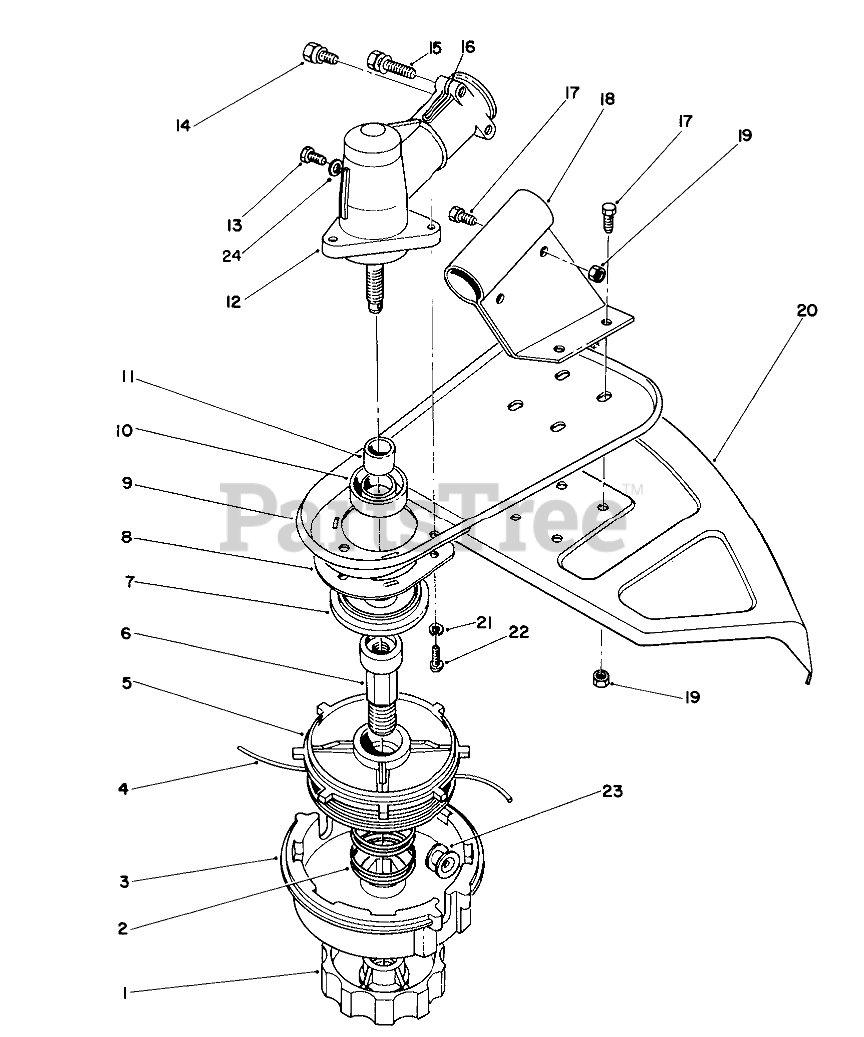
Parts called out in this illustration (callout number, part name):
1	LH KNOB(SERVICE ONLY)
2	SPRING (SERVICE)
3	SPOOL HSG (SERVICE ONLY
5	INNER SPOOL(SERV ONLY)
6	SHAFT (SERVICE ONLY)
7	DUST CAP F/W
8	GRASS WRAP GUARD
9	SHIELD SUPPORT R
10	OIL SEAL
11	SPLINED SLEEVE
12	Gear Box Assembly (Incl. Ref. #10, 11, 13-16 & 24)
13	HHMS SCREW
14	HHMS SCREW
15	HHMS SCREW
16	WASHER
17	SCREW-SHH
18	Bracket-Shield
19	NUT-LOCK, NI
20	GRASS SHIELD-STEEL
21	LOCKWASHER
22	SCREW
23	EYELET(SERVICE)
24	GASKET
